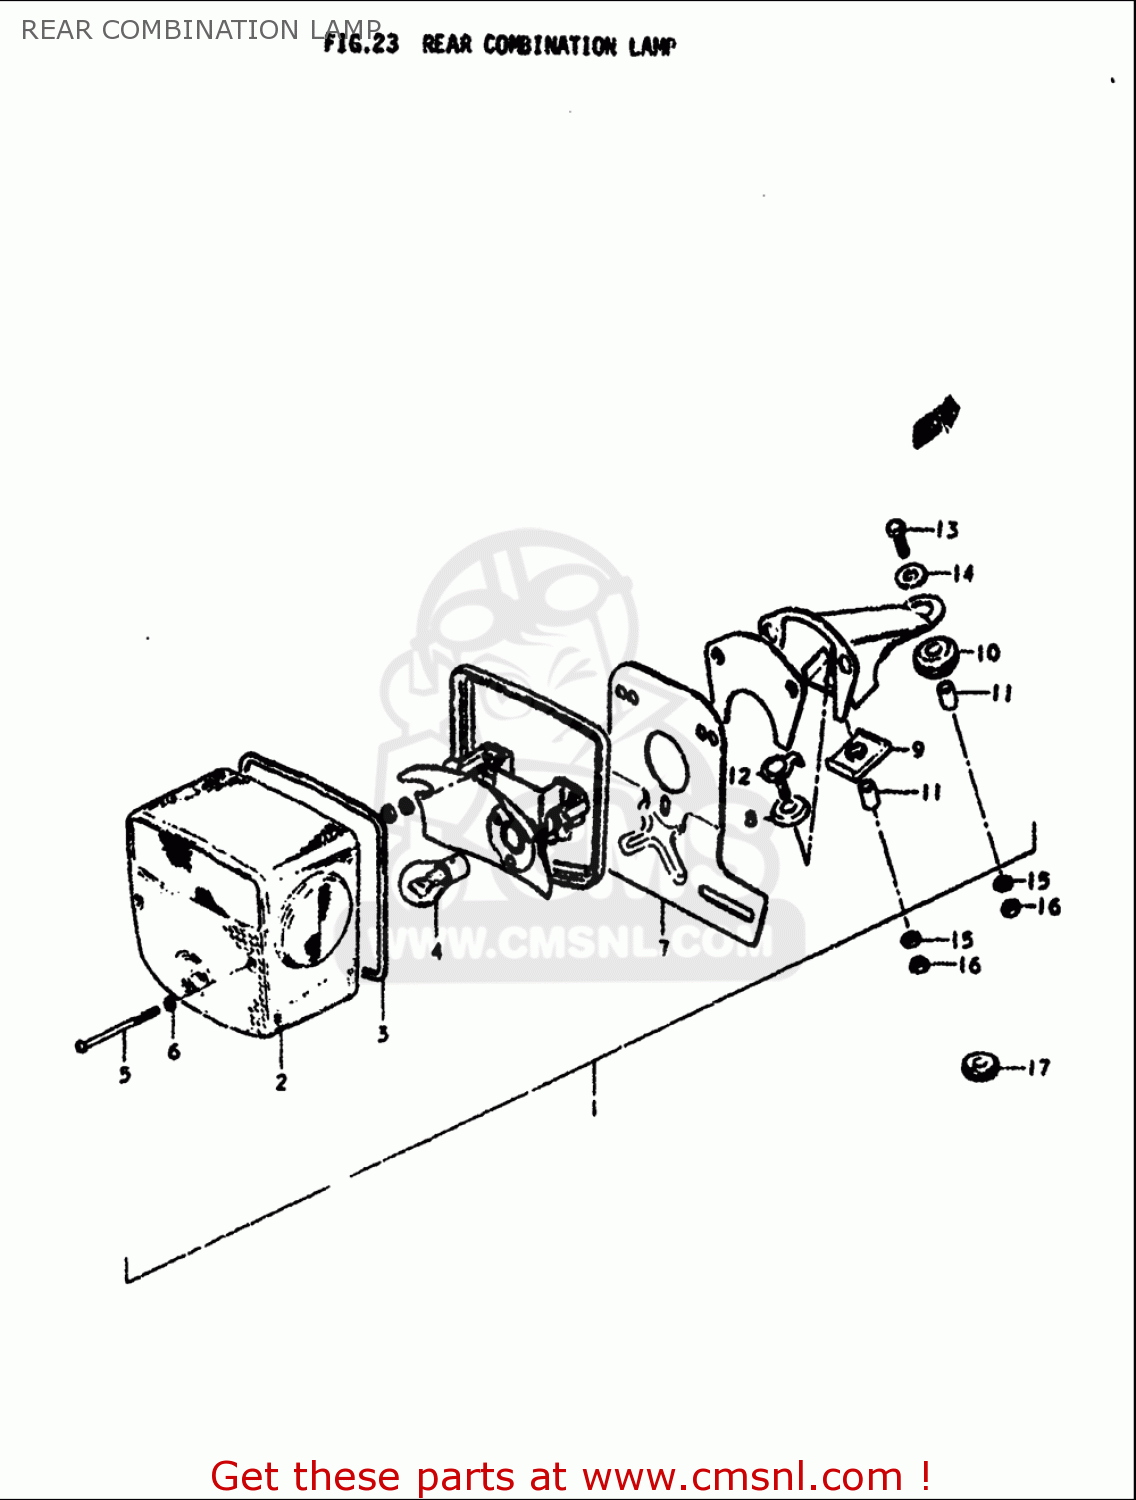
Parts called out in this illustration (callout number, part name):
2	LENS
3	GASKET (NAS)
4	BULB(6V32/3CP,STANLEY)
6	GASKET (NAS)
11	SPACER
13	BOLT
14	WASHER(6.5X20X1.2)
15	WASHER
16	NUT
